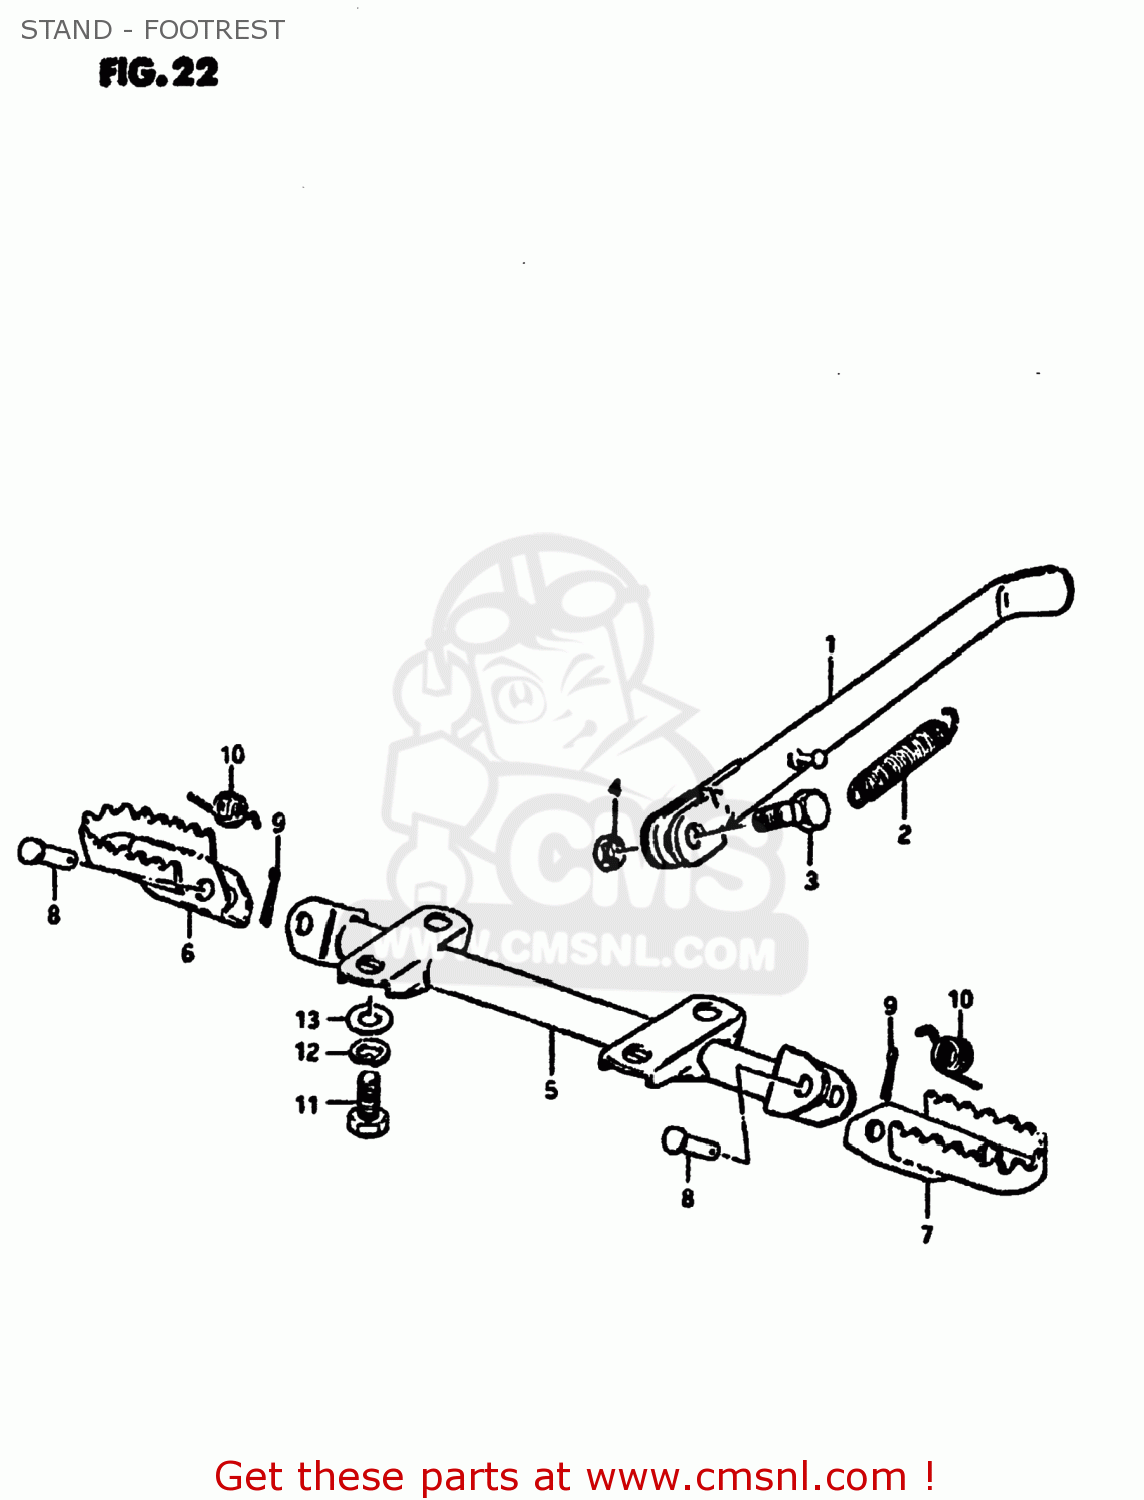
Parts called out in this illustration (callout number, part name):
1	STAND,SIDE
2	SPRING
3	BOLT(10X30)
4	NUT
5	BAR,FR FOOTREST
6	FOOTREST,FR,R
7	FOOTREST
8	PIN
9	PIN 20X20
10	SPRING
11	BOLT
12	LOCK WASHER
13	WASHER
